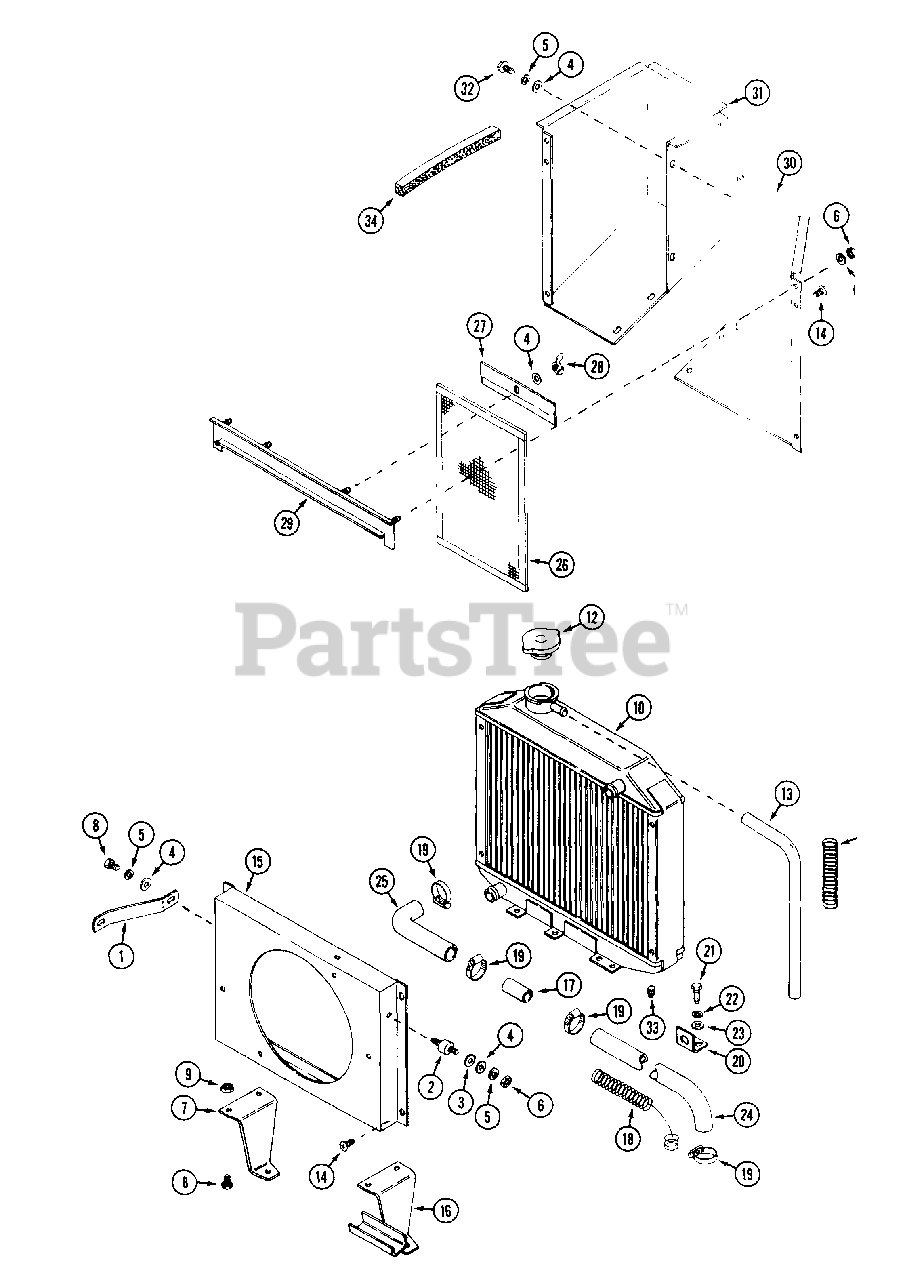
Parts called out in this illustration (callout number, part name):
1	STRAP - radiator mount
2	MOUNT - rubber
3	WASHER - .33" x .69"
4	WASHER - 1/4"
5	LOCKWASHER - 1/4"
6	NUT - 1/4"
7	BRACKET - radiator - support, rear
8	BOLT - 1/4" - 20 x 1/2"
9	NUT - 1/4" - 20 flange lock
10	RADIATOR
12	CAP - radiator
13	HOSE - overflow
14	SCREW - 1/4" - 20 x 5/16"
15	SHROUD - fan
16	BRACKET - radiator support, front
17	TUBE .88" x 2"
18	SPRING - hose liner
19	CLAMP - hose #16
20	BRACKET - hose support, upper
21	BOLT - M8 - 1.25 x 16
22	LOCKWASHER - 5/16"
23	WASHER - .312" x .75"
24	HOSE - .88" x 13.5" top engine
26	SCREEN - radiator
27	BRACKET - screen mounting
28	NUT - wing 1/4" - 20
29	RAIL - upper, screen mounting
30	DUCT - air, front
31	DUCT - air, rear
32	SCREW - 1/4" - 20 x 1/2" flange
33	PLUG - drain
34	SEAL - air intake 13.2"
